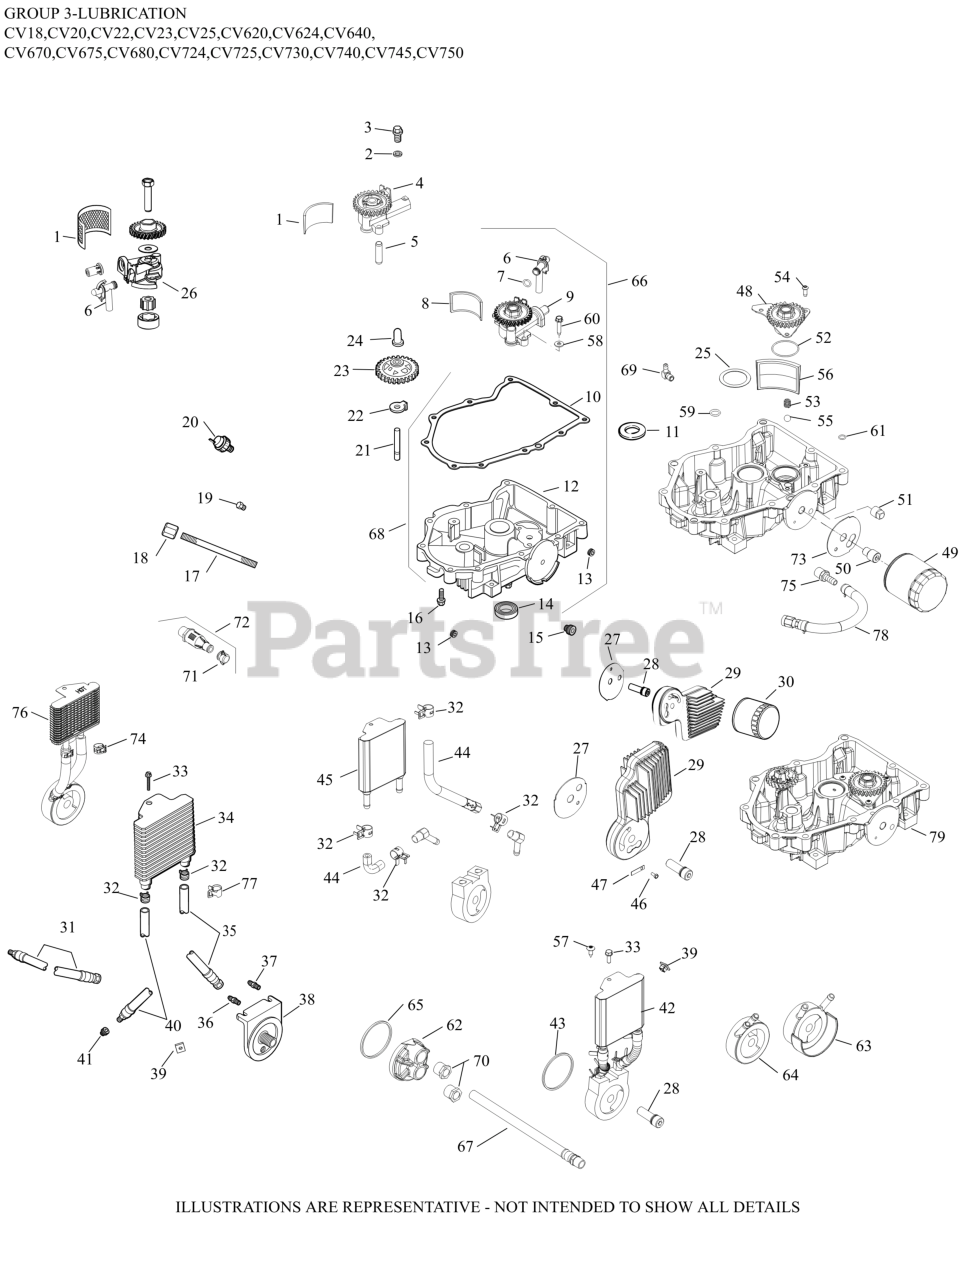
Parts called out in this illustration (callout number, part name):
10	GASKET, OIL PAN
12	KIT, OIL PAN ASSEMBLY
12	PAN, ASSEMBLY OIL (SERVICE)
13	PLUG, PIPE CTSK 3/8"
16	SCREW, FLG M8X1.25X45
20	SENSOR, OIL PSI
21	SHAFT, GOVERNOR GEAR
22	TAB, LOCKING
23	KIT, GOVERNOR GEAR W/PIN
24	PIN, GOVERNOR REGULATING
30	OIL FILTER
48	PUMP, OIL ASSEMBLY
50	NIPPLE, OIL FILTER
51	PLUG, SQ HD PIPE 3/8"
52	O-RING (1.78" DIA)
53	SPRING, COMPRESSION
54	SCREW, BUTTON HEAD
55	PRESSURE RELIEF BALL
56	SCREEN, OIL
60	SCREW, HEX FLANGE
